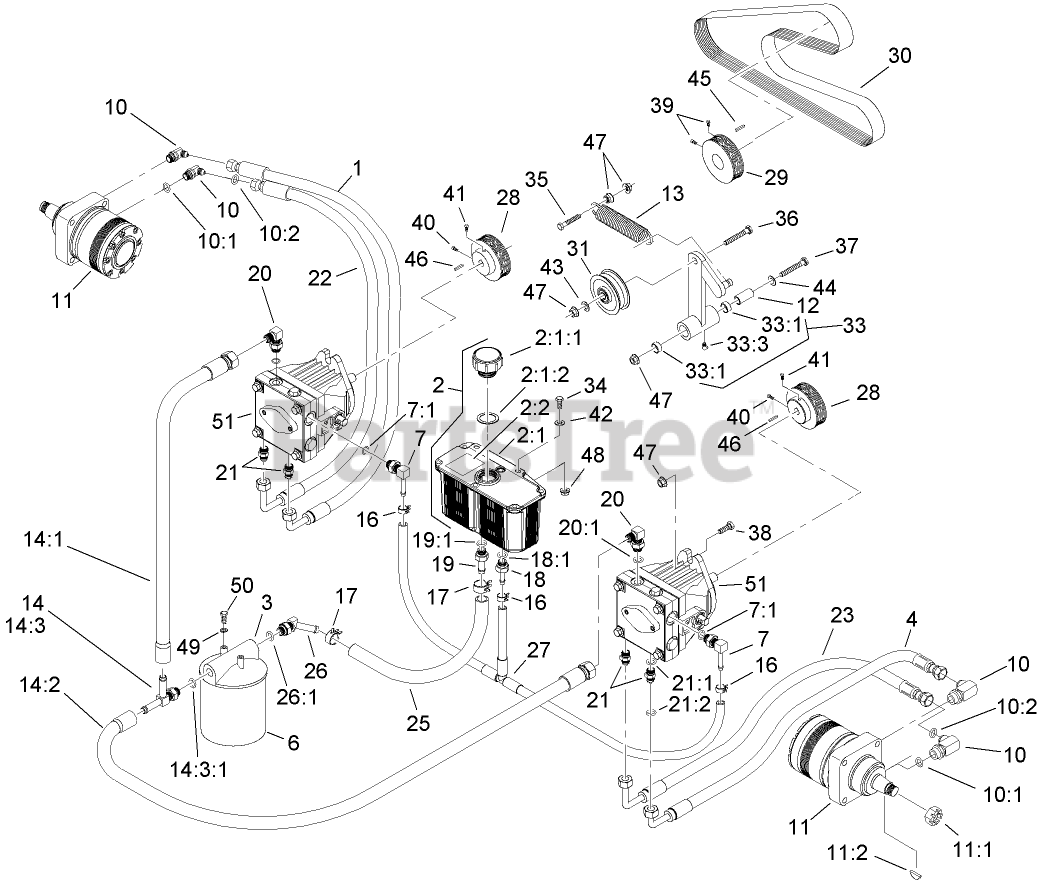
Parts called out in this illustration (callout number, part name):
1	HOSE-RH, UPPER
2	HYD Reservoir ASM
2:1	Reservoir-HYD
2:1:1	CAP-RESERVOIR, HYD
2:1:2	GASKET-CAP
2:2	DECAL-TANK, HYD
3	HEAD-FILTER
4	HOSE-LH, UPPER
6	FILTER-OIL, HYD
6	FILTER-OIL, HYD (WINTER)
7	ELBOW-90 DEG
7:1	O-RING
10	Fitting-Straight
10:1	O-RING
10:2	O-Ring
11	MOTOR-WHEEL
11:1	NUT-HH
11:2	KEY-WOODRUFF
12	BUSHING-PIVOT, IDLER
13	Spring-Extension
14	PUMP INLET HOSE ASM
14:1	HYD Hose ASM
14:2	HYD Hose ASM
14:3	ADAPTER-RUN, TEE
14:3:1	O-RING
16	Clamp-Hose
17	Clamp-Hose
18	Adapter-Straight
18:1	O-RING
19	ADAPTER-STRAIGHT
19:1	O-RING
20	FITTING-ELBOW, 90 DEG
20:1	O-Ring
21	FITTING-STRAIGHT
21:1	O-RING
21:2	O-Ring
22	HOSE-RH, LOWER
23	HOSE-LH, LOWER
25	Hose-HYD
26	FITTING-BARBED, 45 DEG
26:1	O-RING
27	HYD Hose ASM
28	SHEAVE
29	SHEAVE
30	BELT-V
31	SHEAVE-IDLER
33	BEARING ARM ASM
33:1	SLEEVE-BEARING
33:3	FITTING-GREASE, 90 DEG
34	SCREW-HH
35	SCREW-HH
36	SCREW-HH
37	SCREW-HH
38	SCREW-HH
39	SCREW-SET
40	SCREW-SET
41	SCREW-SET
42	WASHER-FLAT
43	WASHER-FLAT
44	WASHER-FLAT
45	KEY-SQUARE
46	KEY-SQUARE
47	NUT-HHF, WHIZ
48	NUT-HF
49	WASHER-LOCK
50	SCREW-HH
51	PUMP-HYD
